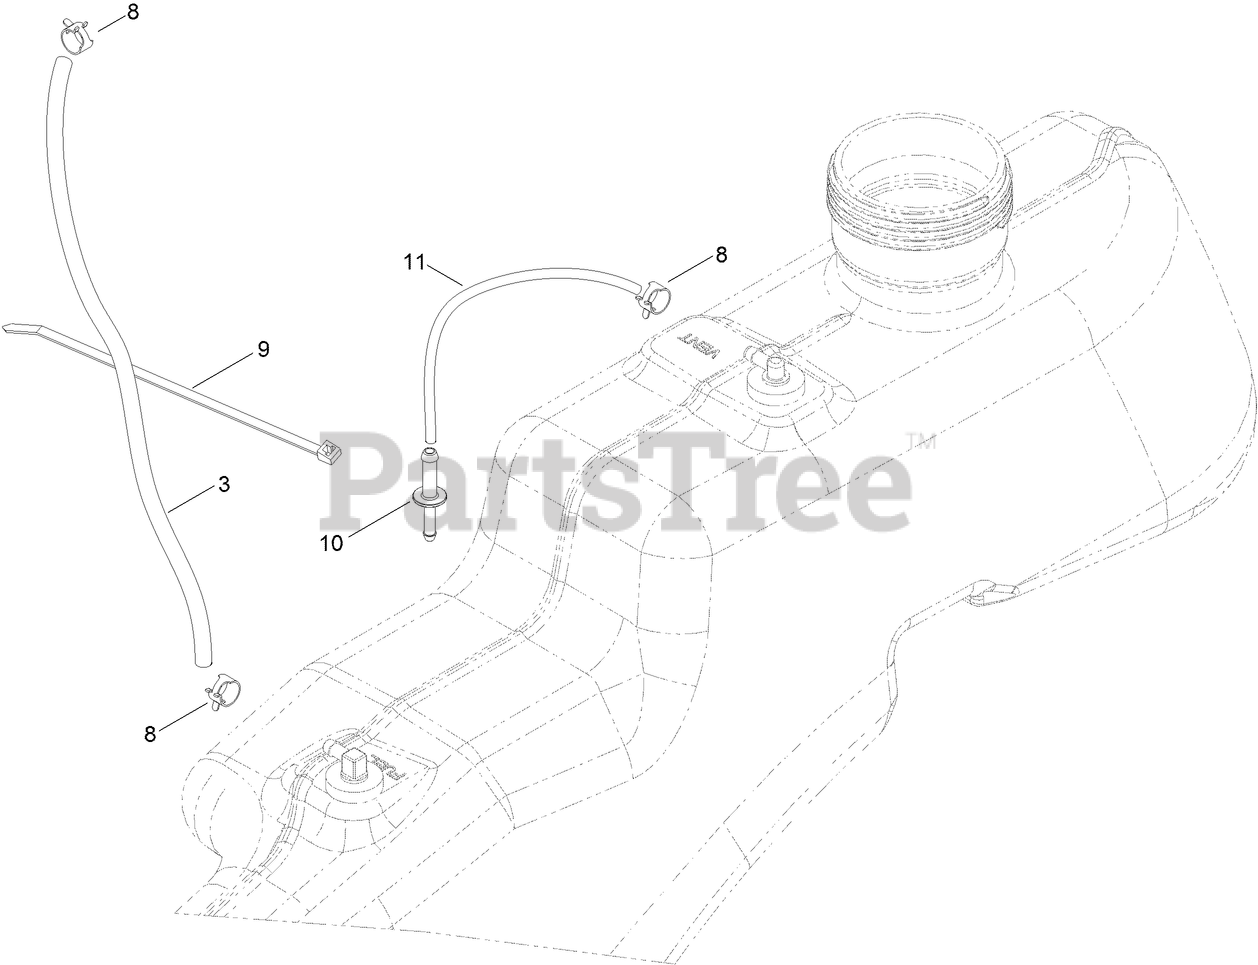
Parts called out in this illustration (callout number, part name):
3	HOSE-FUEL
8	CLAMP-HOSE
9	TIE-CABLE
10	ADAPTOR-ORIFICE
11	HOSE-FUEL
